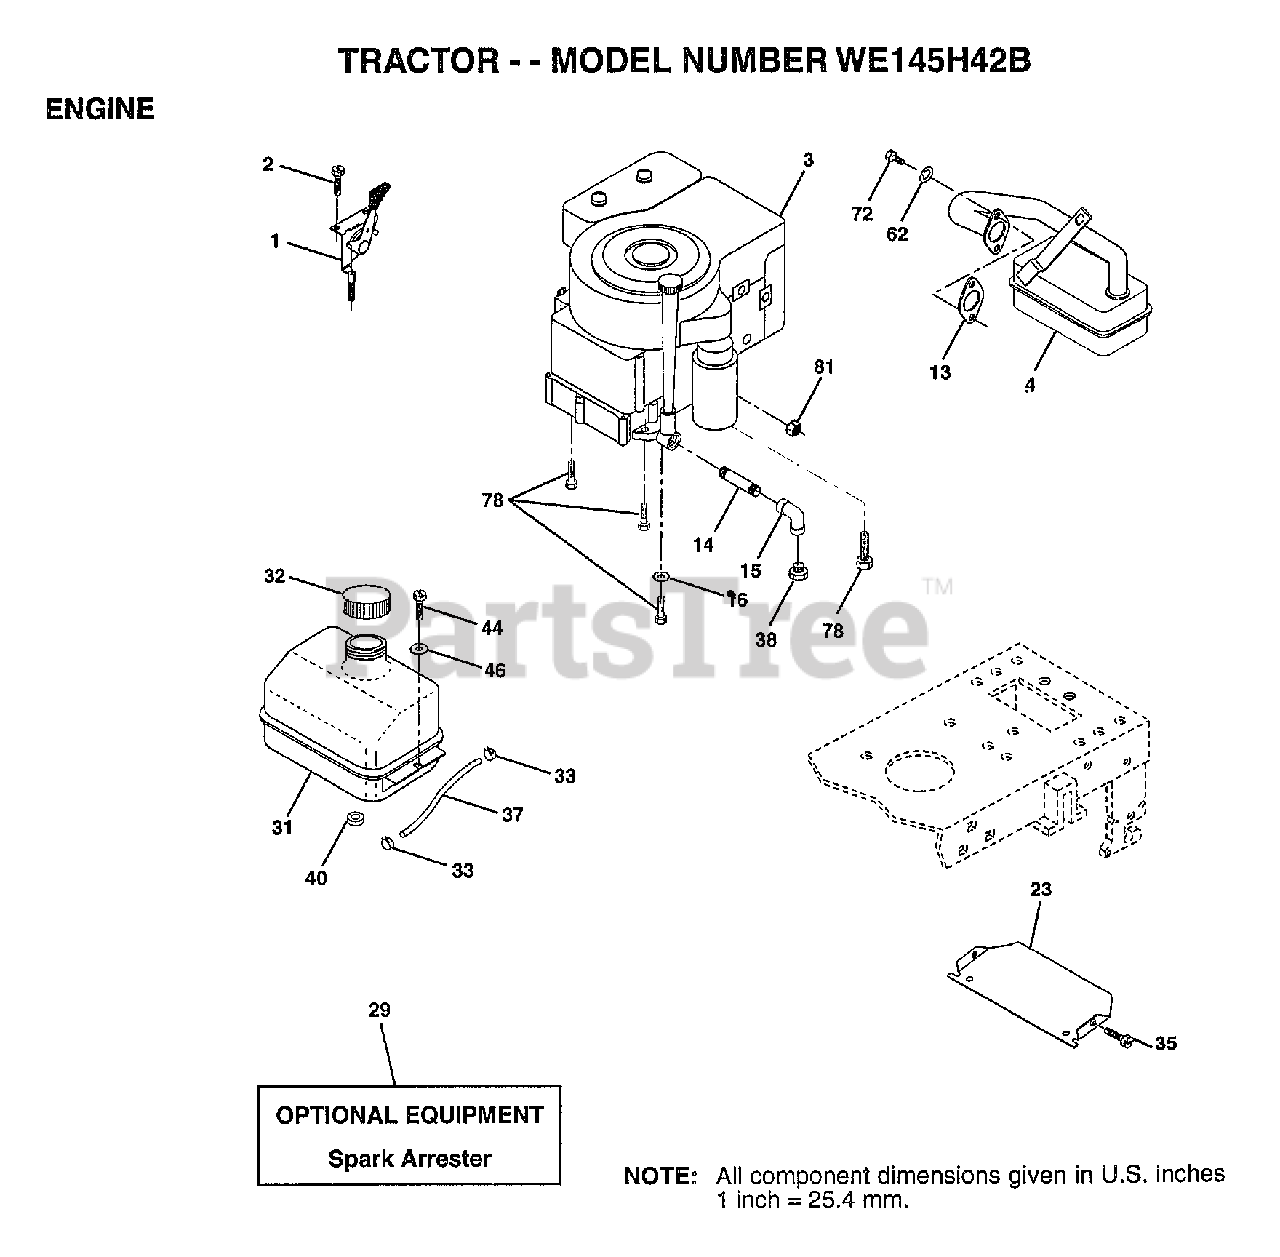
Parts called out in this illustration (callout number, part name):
1	CONTROL THROTTLE
2	SCREW LT
4	MUFFLER
13	GASKET ENG 1 313 LD TIN PLATED
14	PIPE NIPPLE
15	ELBOW
16	LOCKWASHER
23	SHIELD-HEAT
31	TANK.FUEL.LT.
32	CAP ASM FUEL
33	HOSE CLAMP
35	SCREW
37	LINE FUEL
44	SCREW HEX CRT
46	WASHER
62	LOCKWASHER
72	SCREW
78	SCREW
81	NUT
